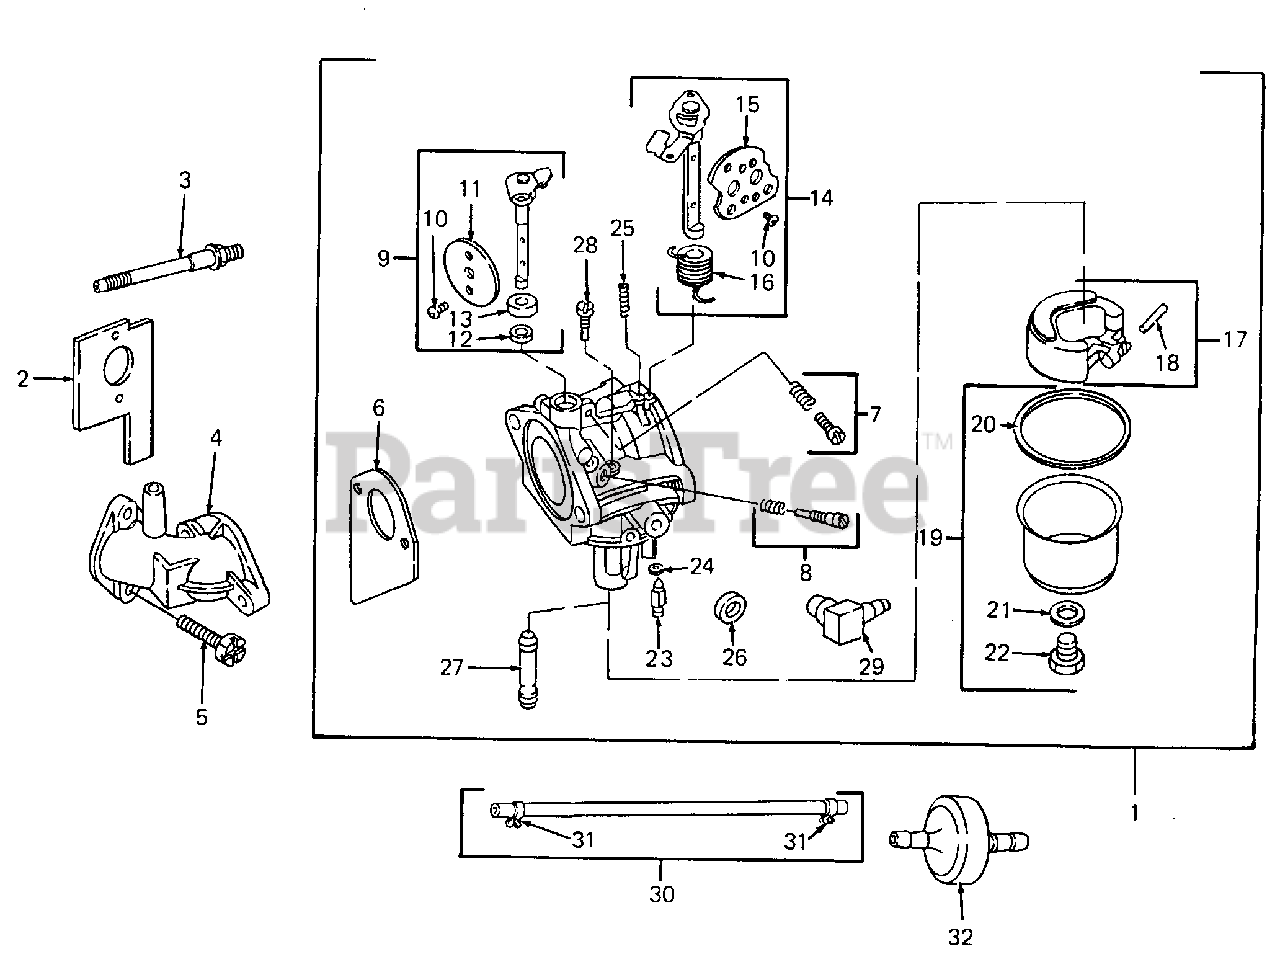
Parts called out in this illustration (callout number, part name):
1	Carburetor Assembly
2	Gasket, Carburetor Mounting
3	Stud, Carburetor Mounting
4	Carburetor, Elbow
5	Screw, Elbow Mounting
6	Gasket, Carburetor
7	Screw, Idle Speed
8	Valve, Needle
9	Shaft & Lever, Throttle
10	Screw
11	Valve, Throttle
12	Washer, Throttle Shaft
13	Seal, Throttle Shaft
14	Shaft & Lever, Choke
15	Valve, Choke
16	Seal, Choke Shaft
17	Float, Carburetor
18	Pin, Float Hinge
19	Bowl Assy, Carburetor
20	Gasket, Float Bowl
21	Washer, Float Bowl Screw
22	Screw, Fuel Bowl
23	Valve Assy, Inlet Needle
24	Seat, Inlet Valve
25	Spring, Choke Stop
26	Plug, Welch
27	Nozzle/Jet, Carburetor
28	Pilot, Jet
29	Tube, Fuel Inlet
30	Line, Fuel, 11" Lg
31	Clamp, Fuel Pipe
32	Filter, Fuel
